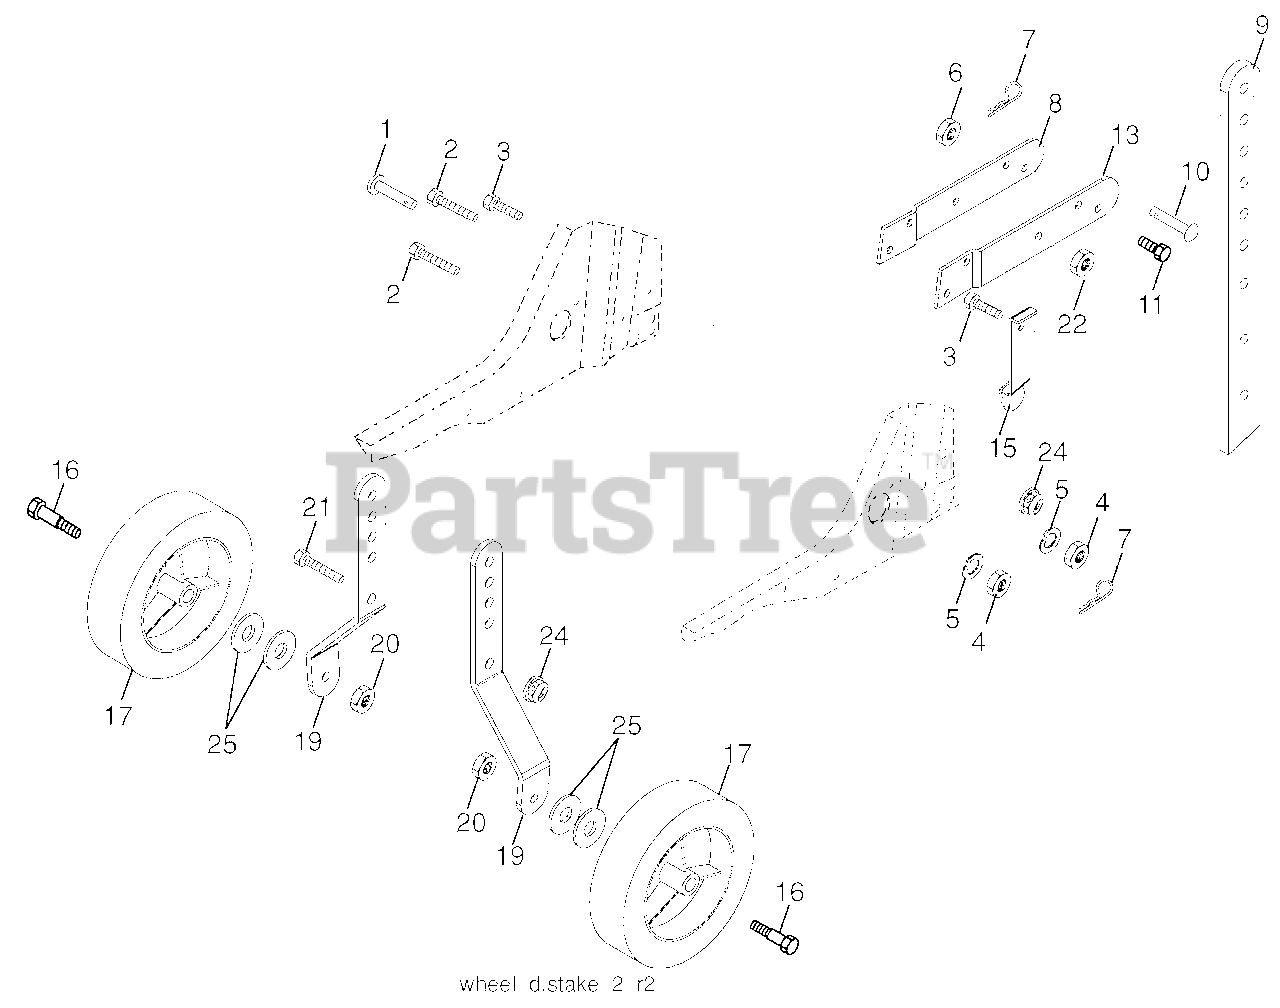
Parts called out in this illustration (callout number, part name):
1	Pin, Clevis
2	Bolt, Hex Head 5/16-18 x 1-1/4
3	Bolt, Hex Head 5/16-18 x 3/4
4	Nut, Hex 5/16-18
5	Washer, Lock 5/16
6	Locknut, Washer Insert 3/8-16
7	Clip, Hairpin
8	Support, Depth Stake, R.H.
9	Stake, Depth
10	Pin, Clevis
11	Bolt, Hex Head 3/8-16 x 1-3/4
13	Support, Depth Stake, L.H.
15	Spring, Stake
16	Bolt, Shoulder
17	Wheel
19	Bracket, Wheel
20	Nut, Hex, Crownlock 3/8-16
21	Bolt, Hex Head 5/16-18 x 1
22	Locknut, Washer Insert 5/16-18
24	Nut, Hex, Flangelock
25	Washer, 17/32 x 7/8 x 16 Ga.
